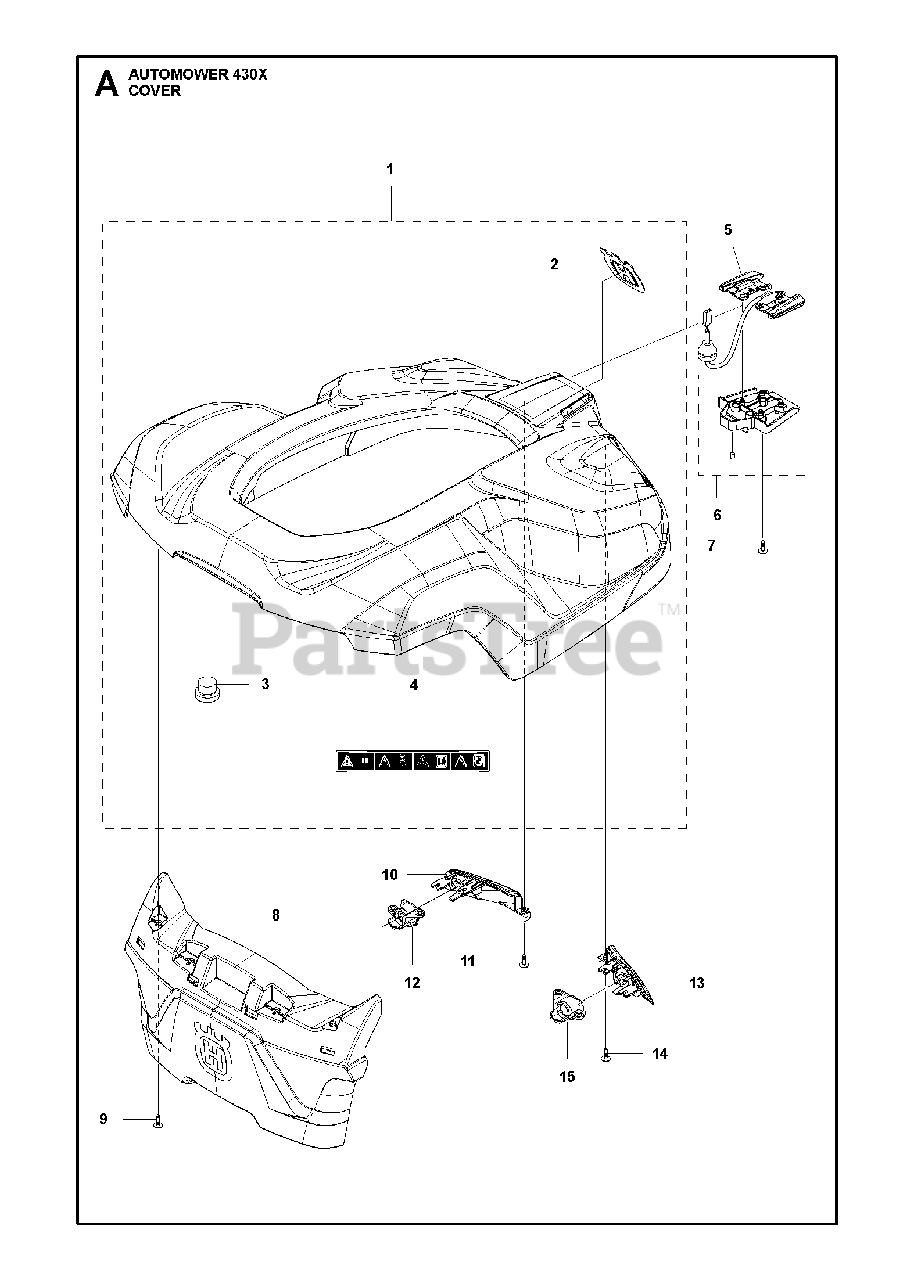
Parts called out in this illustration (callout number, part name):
1	BODY KIT GREY
2	DECAL HUSQVARNA CROWN HEIGHT 5
3	CAP SNAPLOC
4	LABEL WARNING P15
5	LOOM CHARGING PLATE
6	HOLDER ASSY MAGNET
7	SCREW 14MM
8	BUMPER REAR
9	SCREW ITXPANT
10	INSERT US-SENSOR LEFT - GREY
11	SCREW 14MM
12	HOLDER
13	INSERT US-SENSOR RIGHT - GREY
14	SCREW 14MM
15	HOLDER US-SENSOR RIGHT, BLANK
